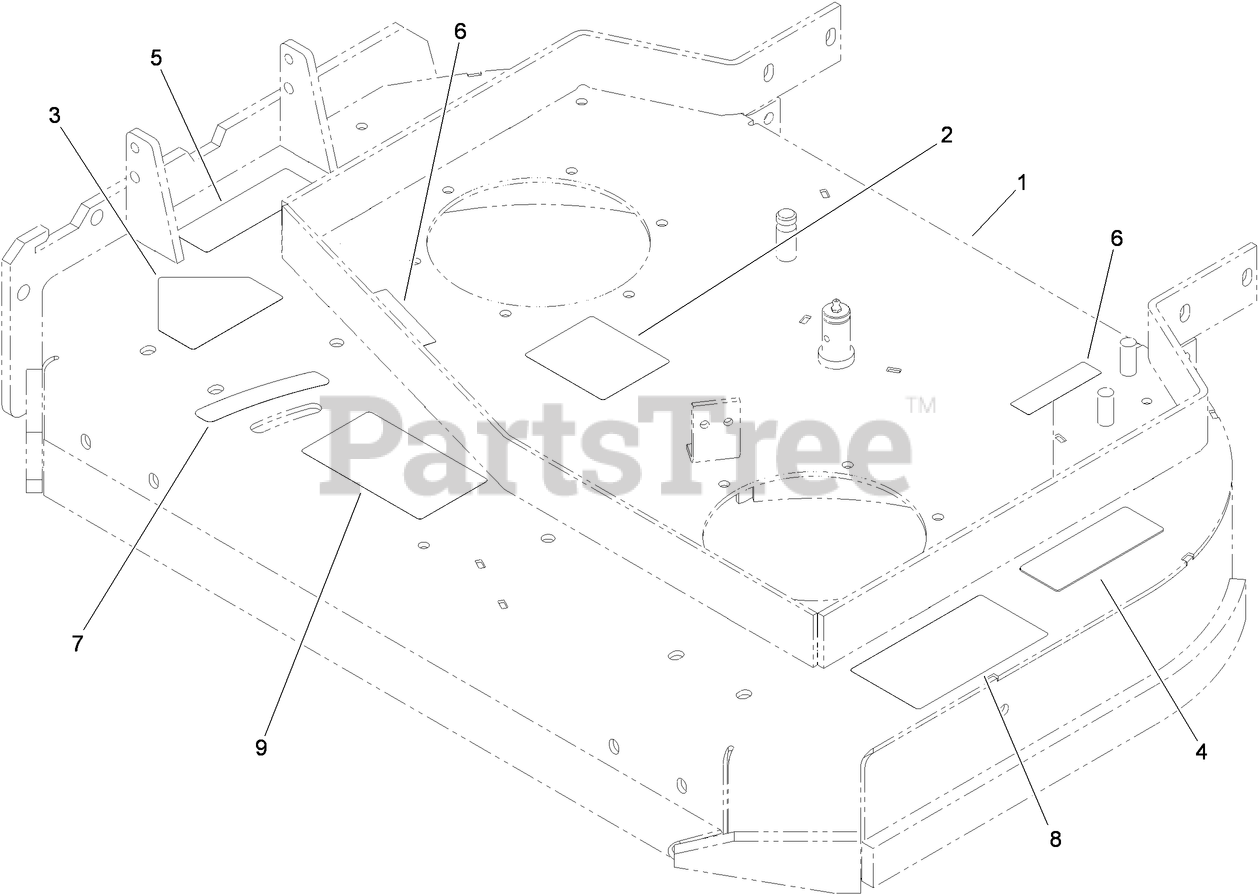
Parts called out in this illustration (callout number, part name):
1	36 INCH DECK ASM
2	DECAL-ROUTING, BELT
3	DECAL-DANGER
4	DECAL-TORQUE, BOLT
5	DECAL-WARNING
6	DECAL-COVER, MISSING
7	DECAL-SETTING, BAFFLE
8	DECAL-DANGER, THROWN OBJECT
9	DECAL-ADJUSTMENT, BAFFLE
